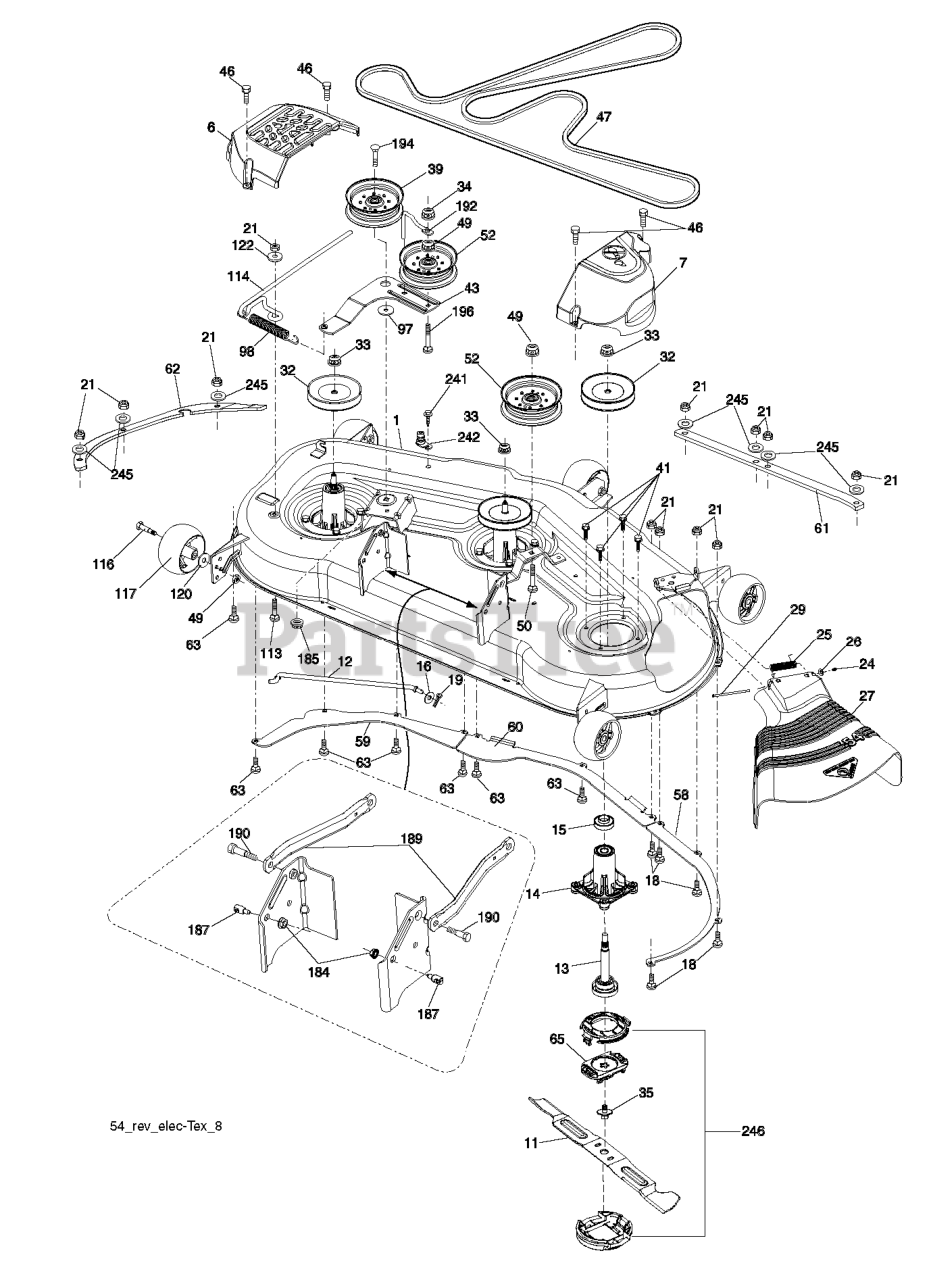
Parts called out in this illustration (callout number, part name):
1	DECK SVC 54"
6	COVER.MANDREL.LH.54"20
7	COVER.MANDREL.RH.54.20
11	BLADE.BAGGER.54"
12	ROD.ANTI.SWAY.48/54"TE
13	MANDREL.ASM.REV.TALL.N/GRSABLE
14	HOUSING.MANDREL.REV.TALL.GRSBL
15	BEARING.MANDREL.TOP.EXTENDED
16	WASHER
18	BOLT
19	PIN.COTTER.5/16.BOW TI
21	LOCKNUT
24	CAP-SLEEVE LT
25	SPRING, TORSION
26	NUT PUSH M
27	DEFLECTOR
29	ROD.HINGE
32	PULLEY/MANDREL
33	NUT.FLANGE.LOCK.TOP
35	SCREW.SEMS.7/16-20X1.HEX.HEAD
39	RB PULLEY.IDLER.4.50/HUB SPEC
41	BOLT.HEX.WASHR.HED.313-18X1.19
43	ARM.IDLER
46	SCREW.1/4-20X5/8
47	BELT.DECK.DRIVE.BELT.54
49	NUT LOCK FLG 3/8-16 UNC
50	BOLT
52	PULLEY.IDLER.2006
58	BAFFLE.RIGHT.54"
59	BAFFLE.LEFT.54"
60	BAFFLE CENTER 54" MOWER
61	PLATE.REIN.FRONT.BOLT54"X431
62	PLATE.REIN.SIDE.BOLT.54"X431
63	BOLT.CARRIAGE.5/16-18
65	HOLDER.BLADE.REVOLUTION
98	SPRING, DECK DRIVE
113	BOLT CRT
114	ROD TENSION RELIEF
116	BOLT.SHOULDER.3/8-16X3-5/8.
117	RP WHEEL. GUAGE RALLY
120	WASHER
122	BUSHING.RELIEF.TENSION
184	NUT LOCK HEX FLANGE 5/16-18
185	NUT.LOCK.FLANGE.7/16
187	STUD.FASTNER.W/ANTI-ROTATE
189	ARM.SUSPENSION.MOWER
190	BOLT.SHOULDER
192	KEEPER.BELT.IDLER.54"T
194	BOLT.HEX.WASHER.HEAD.7/16-24X
196	BOLT
241	SCREW.TT.#10-32X.5.3/8.FLANGE
242	PORT.WASHOUT
245	WASHER
246	CAP.REVOLUTION ASM
